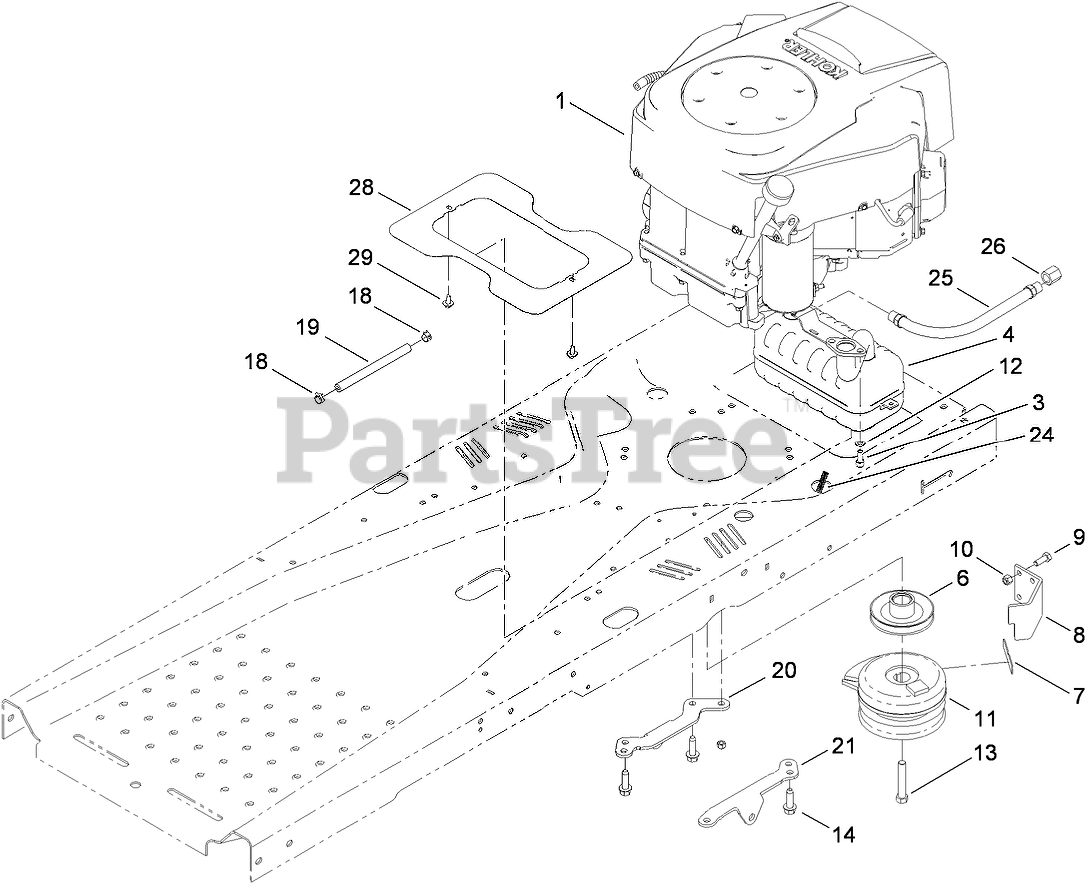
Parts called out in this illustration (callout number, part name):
3	SCREW-HSH
4	MUFFLER-KOHLER TWIN
6	PULLEY-ENGINE
7	BUMPER-PAD
8	STOP-CLUTCH
9	SCREW-HH
10	NUT-LOCK, NI
11	CLUTCH-ELECTRIC, PTO
12	WASHER-LOCK
13	SCREW-HH
14	SCREW-TAPTITE
18	CLAMP-HOSE
19	HOSE-FUEL
20	SUPPORT-HYDRO, RH
21	SUPPORT-HYDRO, LH
24	TUBING-CONVOLUTED
25	HYD HOSE ASM
26	CAP-PIPE
28	SHIELD-HEAT
29	SCREW-HHFTF
